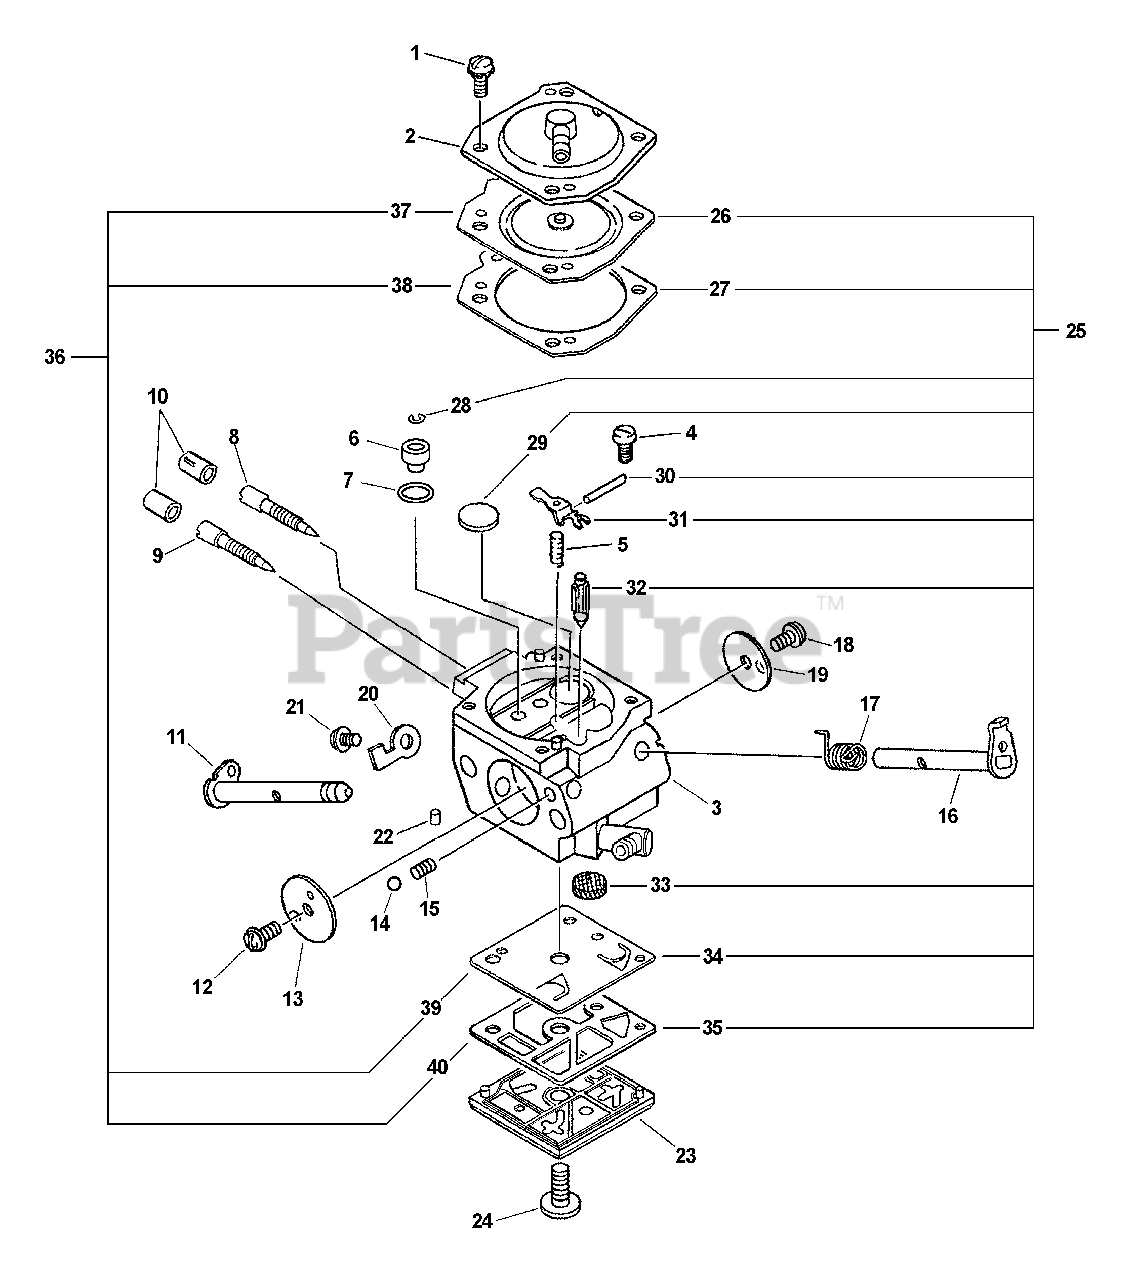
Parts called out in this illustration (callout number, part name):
2	COVER, DIAPHRAGM
3	BODY, CARBURETOR
4	SCREW, METERING LEVER PIN
5	SPRING, METERING LEVER
6	JET, MAIN - 42
8	NEEDLE - MIXTURE
9	NEEDLE - HIGH SPEED
10	CAP, LIMITER
11	LEVER, CHOKE
13	VALVE, CHOKE
14	BALL, CHOKE
16	SHAFT, THROTTLE
17	SPRING, THROTTLE RETURN
19	VALVE, THROTTLE
20	STOP, THROTTLE
23	COVER, PUMP
24	SCREW, PUMP COVER
25	REPAIR KIT
26	DIAPHRAGM, METERING
27	GASKET, DIAPHRAGM
28	RING, RETAINING
29	PLUG, WELCH
30	PIN, METERING LEVER
31	LEVER, METERING
32	VALVE, INLET NEEDLE
33	STRAINER
34	DIAPHRAGM, PUMP
35	GASKET, PUMP
36	DIAPHRAGM/GASKET KIT
37	DIAPHRAGM, METERING
38	GASKET, DIAPHRAGM
39	DIAPHRAGM, PUMP
40	GASKET, PUMP
